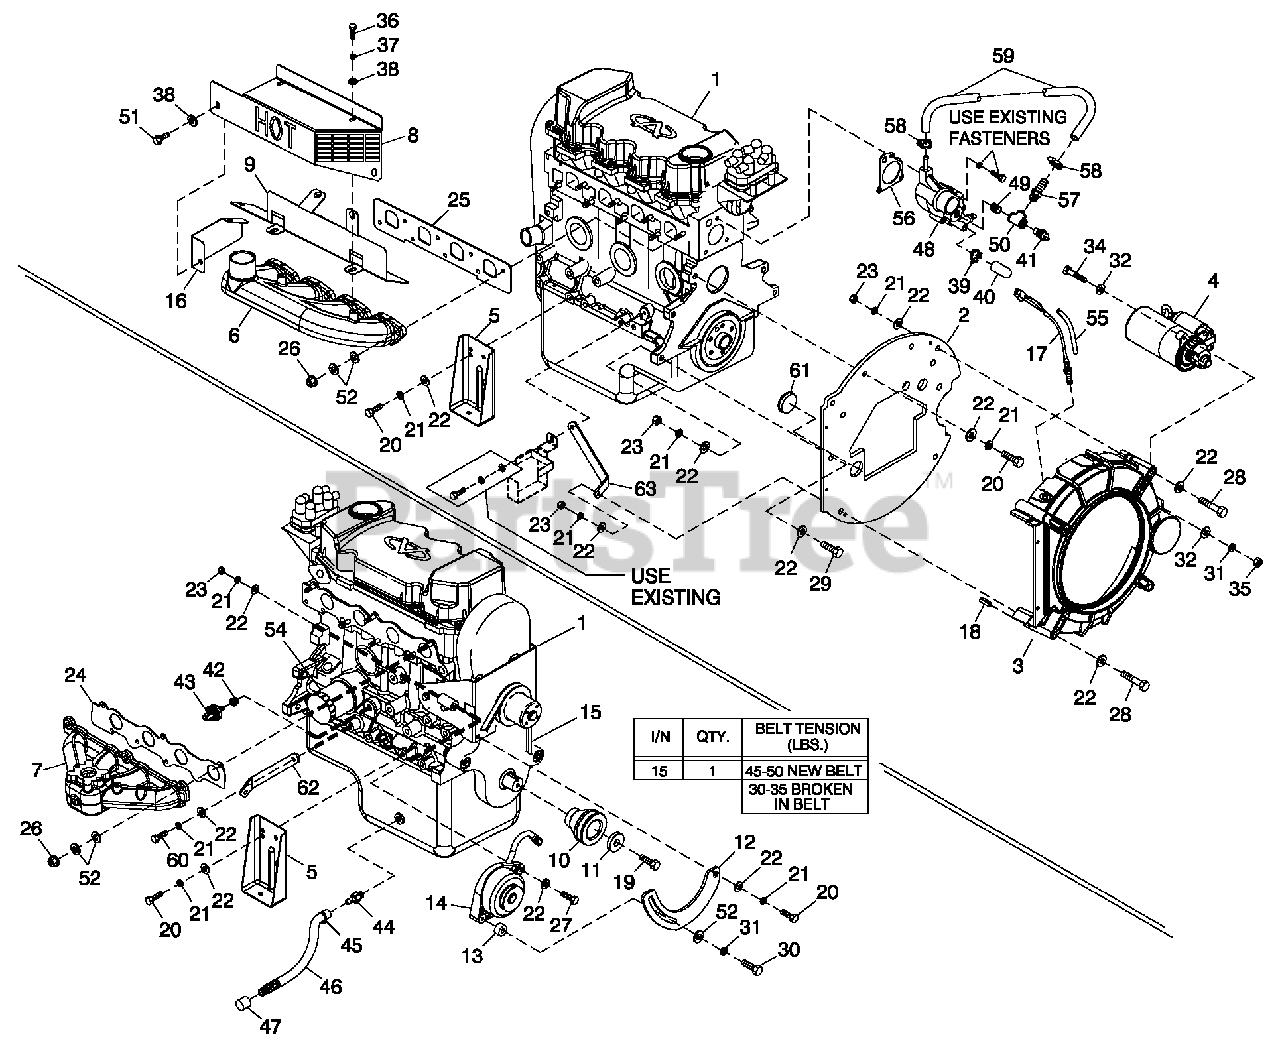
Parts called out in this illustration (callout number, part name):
1	ENGINE GENERAC1.6L NG
2	ENGINE PLATE 1.6L
3	HOUSING BLOWER MACHINED 1.6L
4	STARTER 12 VOLT
5	ENGINE MOUNTING FOOT STAMPING
6	EXHAUST MANIFOLD 1.6L MACHINED
7	INTAKE MANIFOLD MACHINED 1.6L
8	HEAT SHIELD LOWER 1.6L
9	HEAT SHIELD UPPER 1.6L
10	PULLEY CRANKSHAFT MACHINED
11	WASHER PULLEY
12	BRACKET TENSIONER
13	SPACER ALTERNATOR
14	DC ALTERNATR HAN-KOK
15	V-BELT 3/8X30.6
16	HEAT SHIELD FRONT 1.6L
17	ASSY MAGPICKUP(3/8-24 MALE)
18	PIN SPRING 1/4 X 3/4
19	SCREW HHC M12-1.5 X 40 G10.9
20	SCREW HHC M10-1.5 X 25 G10.9
21	WASHER LOCK M10
22	WASHER FLAT 3/8-M10 ZINC
23	NUTHEXM10-1.5 CLASS 10 ZINC
24	GASKET INTAKE MANIFOLD 1.6L
25	GASKET EXHAUST MANIFOLD 1.6L
26	NUT TOP LOCK FL M8-1.25
27	SCREW HHC M10-1.5X 85 G8.8
28	SCREW HHC M10-1.5X 110 G10.9
29	SCREW HHC M10-1.5 X 40 G10.9
30	SCREW HHC M8-1.25X 35 G8.8
31	WASHER LOCK M8-5/16
32	WASHER FLAT 5/16-M8 ZINC
33	TIE WRAP UL 7.4" X .19" BLK
34	SCREW HHC M8-1.25X 40 G8.8
35	NUT HEX M8-1.25 G8 CLEAR ZINC
36	SCREW HHC 1/4-20 X 1/2 G5
37	WASHER LOCK M6-1/4
38	WASHER FLAT 1/4-M6 ZINC
39	CLAMP HOSE #10 .56-1.06
40	CAP ANTIFREEZE RUBBER
41	SWITCH HI-TEMP 245 D X 3/8 NPT
42	BSHG RDCR HEX 1/4 TO 1/8
43	SWITCH OIL PRESSURE 10PSI2POL
44	ADAPTER DRAIN OIL
45	CLAMP HOSE - OIL DRAIN
46	HOSE OIL DRAIN ASSY 21"
47	CAP HEX 1/4 NPT BRASS
48	THERMOSTAT HOUSNG MACHIND 1.6L
49	NIPPLE PIPE 3/8 NPT X 1-1/2
50	PIPE TEE 3/8 NPT
51	SCREW HWHTF M6-1.0X16
52	WASHER FLAT .34 ID X .75 OD
54	OIL FILTER 1.6L
55	REFLEX WRAP 13MM 13 X 460 (6" LG)
56	GASKET T-STAT HOUSING 1.6L
57	BARBED STR 3/8 NPT X 3/8
58	CLAMP HOSE .38-.87
59	HOSE 3/8 ID LOW PRES OIL/WATER (11" LG)
60	SCREW HHC M10-1.5X 20 G8.8
61	CAP, 1.5" HOLE SHALLOW
62	STRUT RH 1.6L ENG ADAPT PLATE
63	STRUT LH 1.6L ENG ADAPT PLATE
